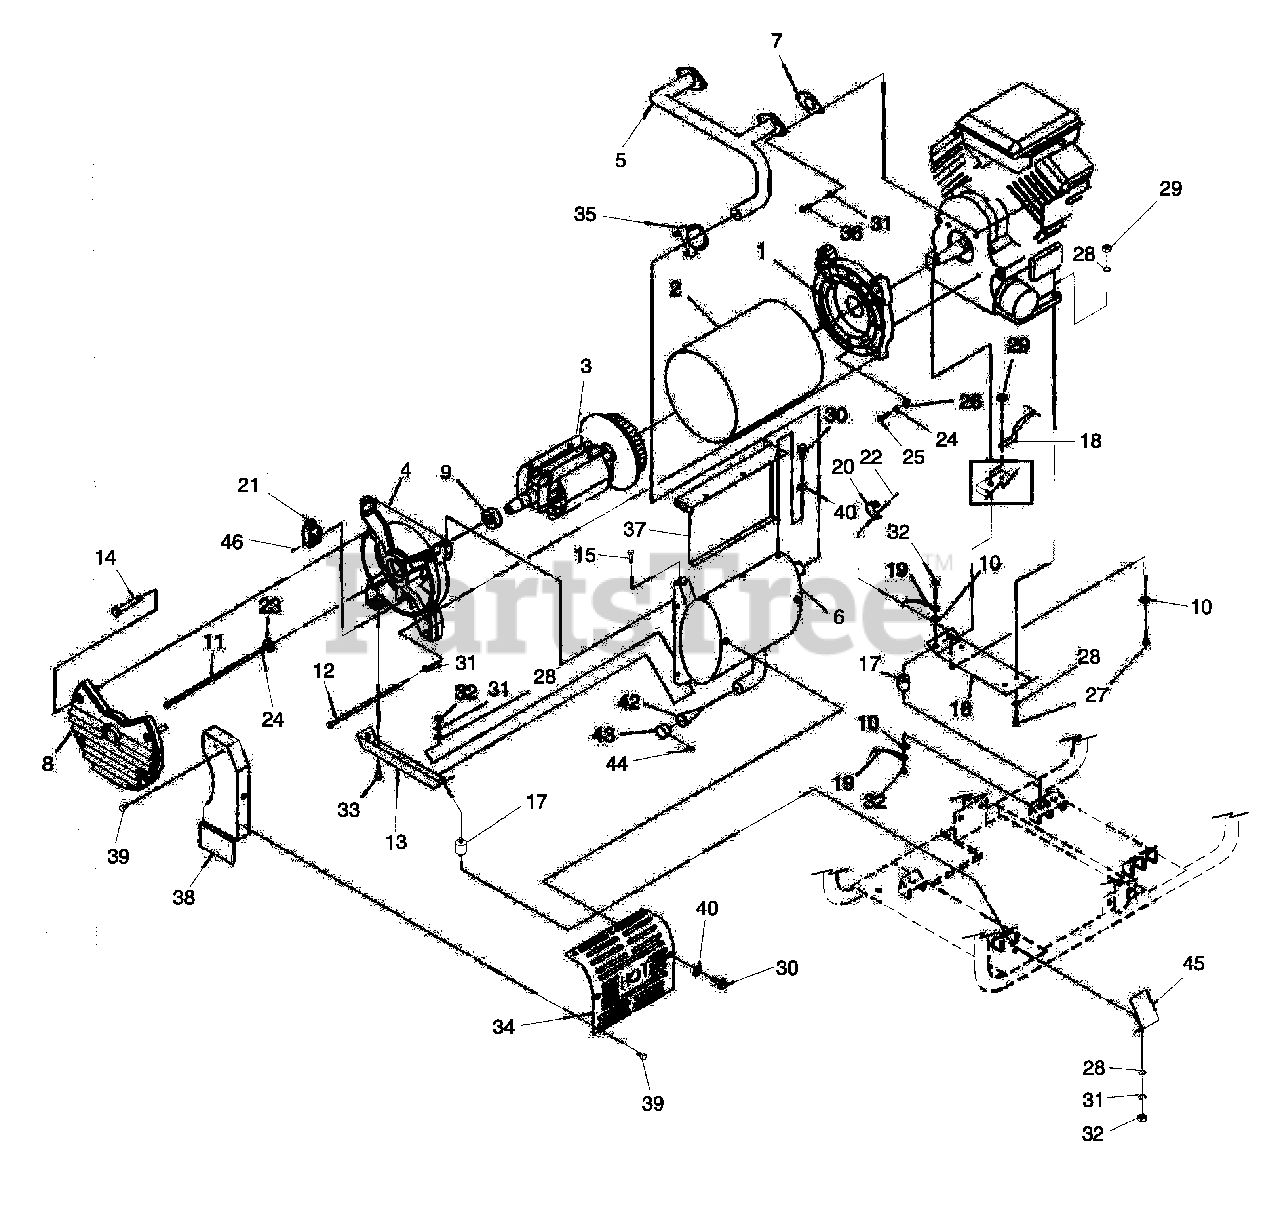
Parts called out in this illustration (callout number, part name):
1	ADAPTOR, ENGINE
2	STATOR 12.5KW
3	ASSEMBLY, ROTOR WITH FAN 12.5KW
4	CARRIER, REAR BEARING
5	EXHAUST MANIFOLD
6	MUFFLER
7	GASKET, EXHAUST
8	COVER, ALTERNATOR AIR IN
9	BEARING
10	5/16 SPECIAL LOCK WASHER
11	SCREW IHHC 3/8-24 X 15.50 G5
12	SCREW IHHC M8-1.25 X 400 G8.8
13	BRACKET, ALT MOUNTING
14	SCREW HHTT #10-32 X 1.75
15	SCREW HHTT M8-1.2 X 20
16	ENGINE MOUNTING PLATE
17	RUBBER MOUNT
18	BATTERY CABLE, BLACK
19	EARTH STRAP 3/8X 3/8
20	CLIP-J VINYL COAT .625 ID
21	ASSEMBLY, BRUSH HOLDER
22	SCREW TAP-R #10-32 X 9/16
23	WASHER FLAT 3/8 ZINC
24	WASHER LOCK 3/8
25	SCREW HHC 3/8-16 X 1-1/4 G5
26	WASHER FLAT 3/8-M10 ZINC
27	SCREW HHC M8-1.25 X 50 G8.8
28	WASHER FLAT 5/16 ZINC
29	NUT LOCK HEX M8-1.25 NYLON INSERT
30	SCREW HHC M6-1.0 X 16 WITH LOCK WASHER
31	WASHER LOCK M8-5/16
32	NUT HEX 5/16-18 STEEL
33	SCREW TAPTITE 3/8-16 X 3/4 BP
34	SHIELD, MUFFLER HEAT
35	U-BOLT & SADDLE
36	SCREW SHC M8-1.25 X 18
37	PANEL, MUFFLER BOX BACK
38	PANEL, MUFFLER BOX END
39	SCREW HHTT M6-1.0 X 12
40	WASHER FLAT 1/4
42	SPARK ARRESTOR SCREEN
43	RETAINER, SPARK ARREST SCREEN
44	SCREW HHTT M4-0.7 X 8
45	SHIELD, RUBBER MOUNT
46	SCREW HHTT M5-0.8 X 16
